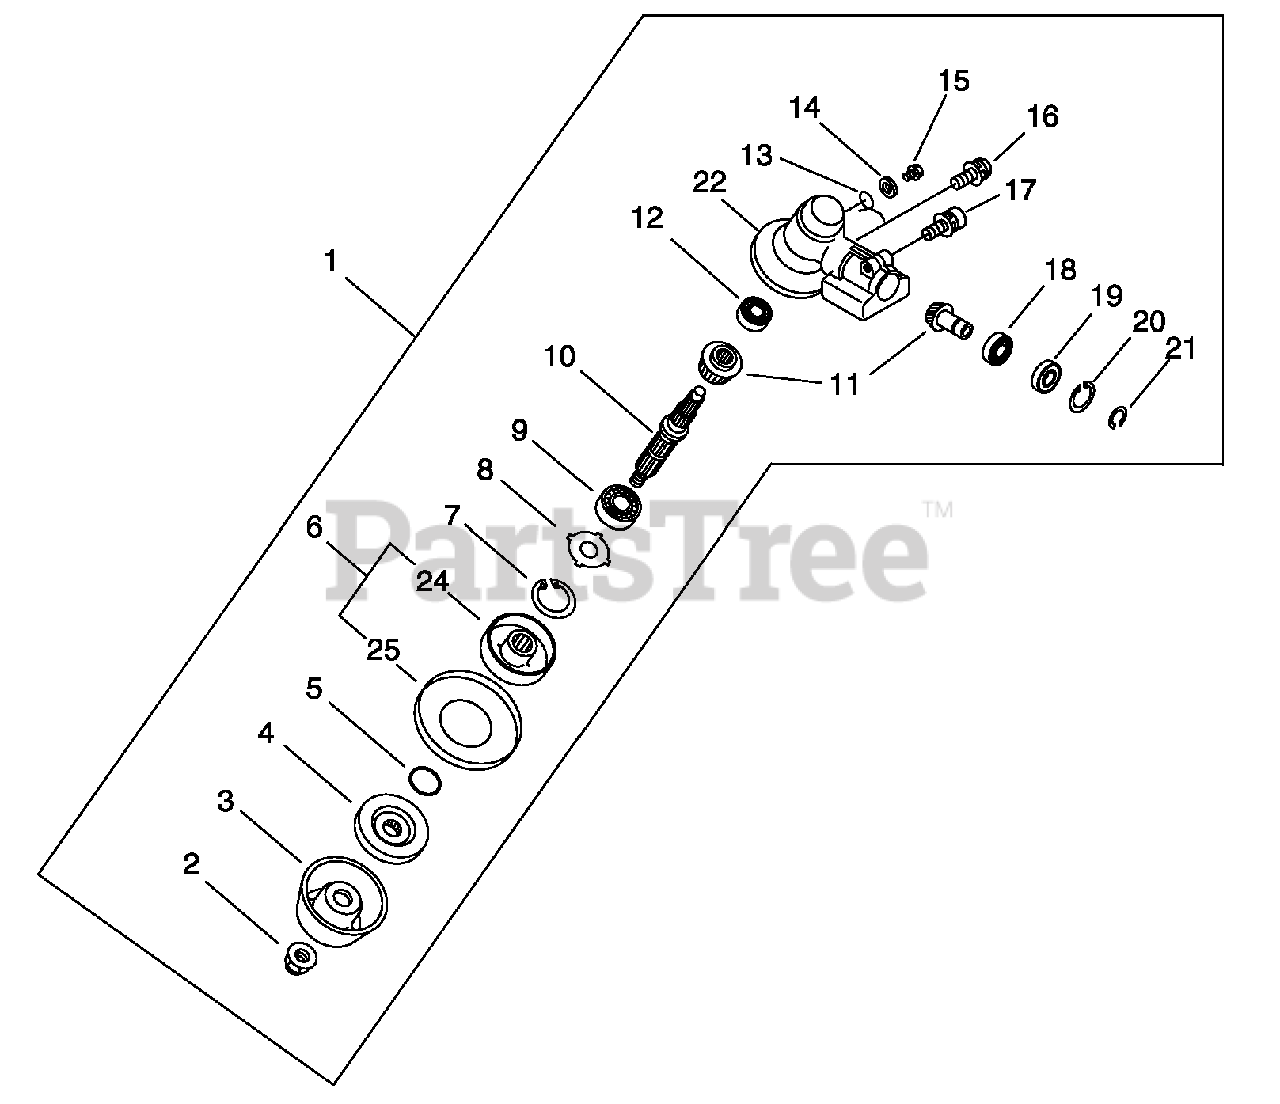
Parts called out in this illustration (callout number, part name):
1	GEAR CASE ASSY
2	NUT, LOCK 10 - NYLON INSERT
4	PLATE, ADAPTOR - LOWER
5	O-RING 12 MM
6	RETAINER, BLADE
7	RING, SNAP Ø32
9	BEARING, BALL 6201
10	SHAFT, GEAR
11	GEAR SET
12	BEARING, BALL 626
13	SPRING, TORSION
14	WASHER 8.5×18×0.8T
15	BOLT M8×8
16	SCREW 5×10
18	BEARING, BALL 6900
19	BEARING, BALL 6900Z
20	RING, SNAP Ø22
21	RING, SNAP Ø10
22	CASE, GEAR
24	PLATE, ADAPTOR
25	PLATE, ADAPTOR - LOWER
